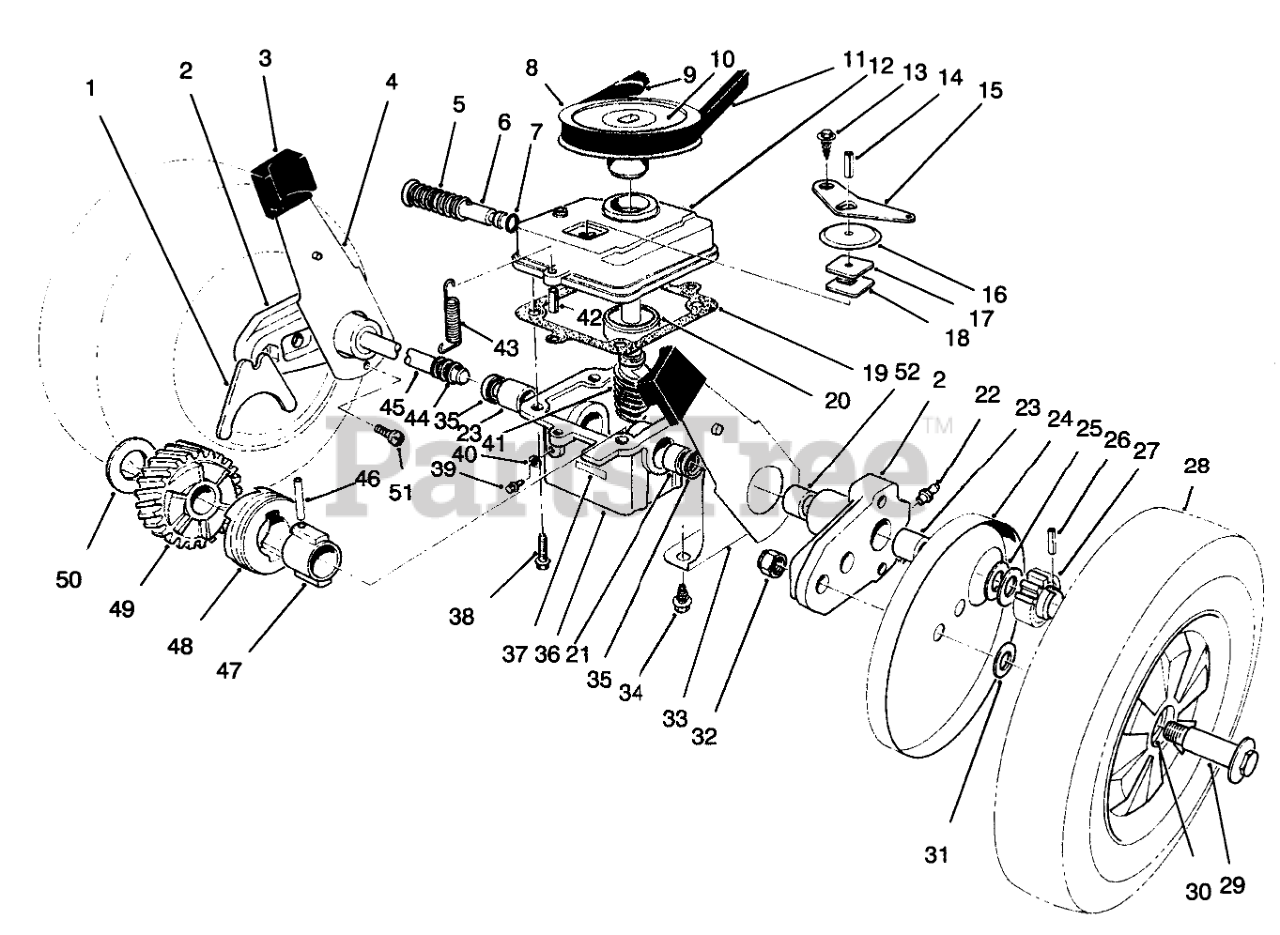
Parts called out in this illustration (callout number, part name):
1	SHIFTER FORK
2	Arm-Pivot (Incl. Ref. #22, 23 & 52)
3	KNOB-ARM
4	SPRING ARM ASSY-FRONT
5	SPRING
6	SHIFTER ROD
7	O-RING
8	PULLEY
9	NUT - PUSH
10	DECAL
11	V BELT
12	GEAR CASE COVER
13	SCREW-HWHTF
14	PIN-ROLL
15	SHIFTER ARM
16	DUST COVER
17	DUST FILTER
18	LATCH PLATE
19	GASKET
20	BEARING
21	BUSHING
22	FITTING-GREASE
23	BUSHING
24	Cover-Wheel
25	THRUST WASHER
26	COIL PIN
27	PINION GEAR 15T
28	Wheel, Tire & Gear Ass-y (Incl. Ref. #30)
29	WHEEL BOLT
30	BUSHING
31	WASHER
32	NUT-LOCK
33	END CAP
34	SCREW-HWHTF
35	SEAL-OIL
36	Gear Case (Incl. Ref. #21, 23, & 35)
37	DECAL
38	SCREW-HWHTF
39	NYLON SCREW
40	FILL PLUG GASKET
41	Worm Shaft & Gear (Incl. Ref. #49)
42	3/16 X 1/2 ROLL PIN
43	TENSION SPRING
44	COVER-SHAFT, DRIVE
45	DRIVE SHAFT
46	COIL PIN
47	SLEEVE
48	CLUTCH JAW
49	Helical Gear
50	THRUST WASHER
51	SCREW
52	BUSHING
